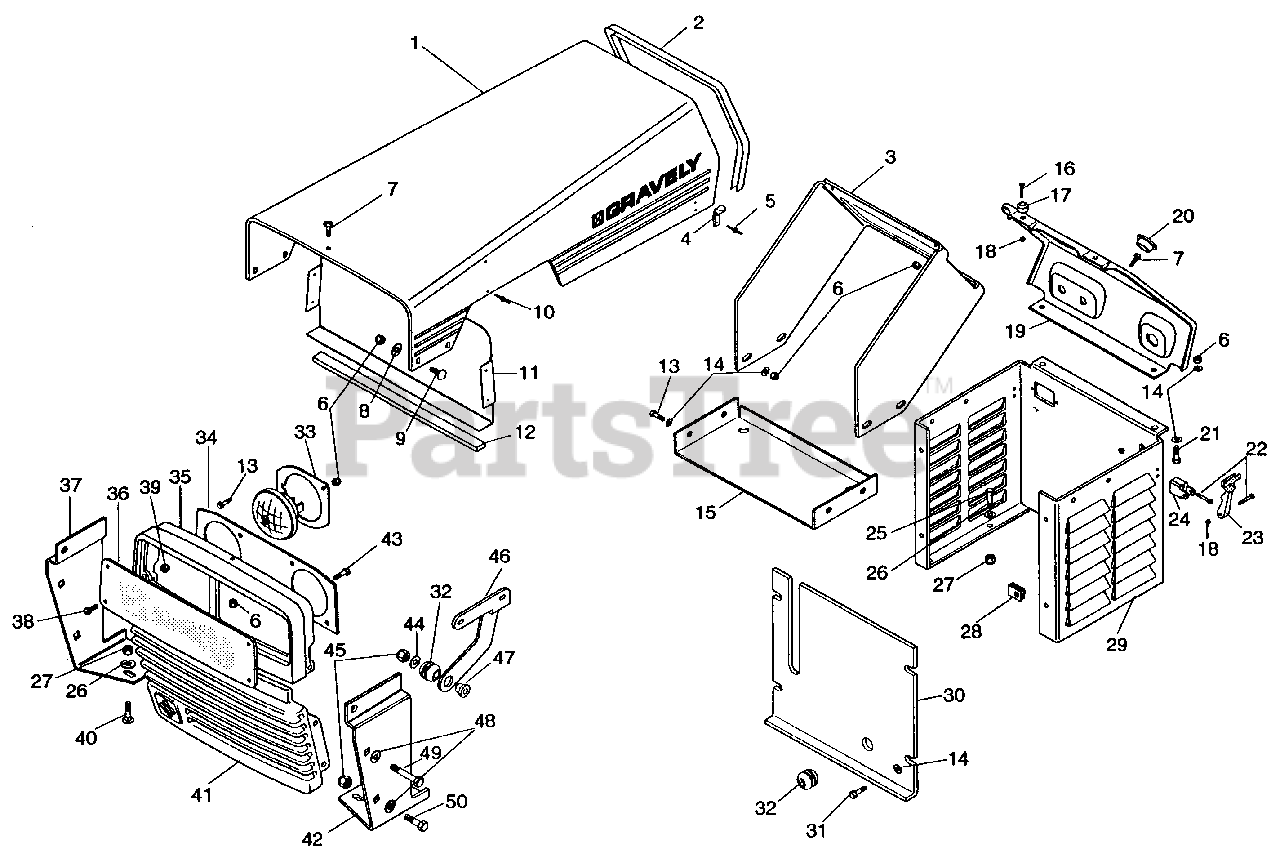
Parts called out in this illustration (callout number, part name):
1	Hood Silkscreen 16 HP Gem
2	Strip, Cowl
3	Bracket, Support
4	Keeper
5	Rvt .125 x .245
6	Nut-Lk-Nyl .250-20 Pl
7	Scr-Mch .25-20 Pan Hd
8	Wshr-Flat .281 x .625 x .065
9	Blt-Rdhdsqnk .25-20 x .75
10	Rvt-Pop .125 x .232
11	Baffle
12	Pad, Baffle
13	Blt-Hex .25-20 x 1.00 Pl Gr 5
14	Wshr-Fl-Stl .281 x .625 x .065
15	Battery Support
16	Scr-Mch 6-32 x .625
17	Bumper
18	Nut-Lk-Mch 6-32 w/insert
19	Dash Silkscreen 16 HP
20	Bshg-Flg .762 x 1.0 x .580 x 1.48 Ny
21	Blt-Hex .25-20 x .63
22	Scr-Mch 6-32 x 1.00
23	Latch, Flexible Draw
24	Block, Tie Down
25	Blt-Hex .31-18 x 1.00 Pl Gr 5
26	Wshr-Fl-Stl .344 x .688 x .065
27	Nut-Lk-Nyl .312-18 Pl
28	Nut-Rtnr .25-20 x .56
29	Dash Tower - Silkscreen
30	Cover, Hydraulic Tank
31	Blt-Hex .25-20 x .75 Pl Gr 5
32	Grommet
33	Head Light Retainer Ring
34	Panel, Headlight Reflector
35	Bezel, Headlight
36	Panel, Headlight Lens
37	Bracket
38	Scr-Mch 10-24 x .750 Phd
39	Nut-Lk 10-24 Ny Pl
40	Blt-Carriage .31-18 x 1.0
41	Grill
42	Bracket LH
43	Scr-Tap .25-20 x .50 Hxslhdpl
44	Wshr-Fl-Stl .438 x 1.000 x .083
45	Nut-Lk-Nyl .375-16 Pl
46	L.H. Hood Hinge
46	R.H. Hood Hinge
47	Spacer
48	Wshr-Fl-Stl .406 x .812 x .065 Pl
49	Blt-Hex .38-16 x 2.00 Pl Gr 5
50	Blt-Hex .38-16 x 1.25 Pl Gr 5
